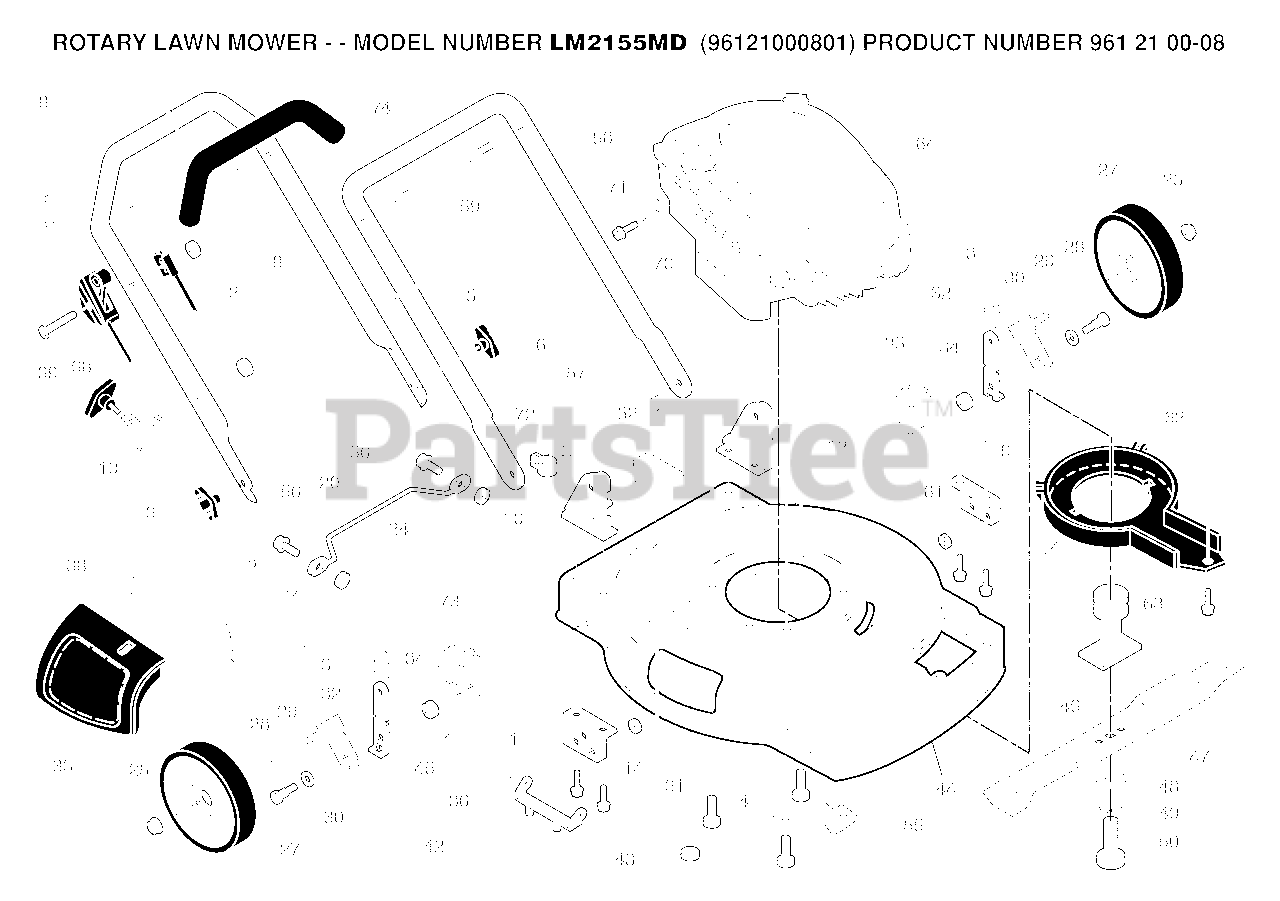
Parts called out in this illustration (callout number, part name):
2	ENGINE ZONE CONTROL CABLE
5	TIE GUIDE
6	KNOB, DEFLECTOR
10	HANDLE BRACKET ASM. RH
12	HANDLE BRACKET ASM. LH
14	SCREW 5/16-18
18	NUT
19	GUIDE.ROPE.STD.BLK.ZIN
25	HEX FLANGE LOCKNT
28	BOLT
29	BELLEVILLE WASHER
30	AXLE ARM
31	SELECTOR KNOB
34	RP SPACER HT ADJ
36	HINGE BRACKET
41	BOLT 3/8-16X1-1/8
42	TORSION SPRING
43	LOCKNUT
45	ROD.HINGE.COMBI-C
46	BLADE ADAPTOR / PULLEY
48	WASHER,HARDEN
49	LOCKWASHER
50	SCREW, HEX HD 3/8-24 X 1-3/8
52	DECAL.INTERNATIONL.CUTFINGER
55	BRACKET
57	HAIRPIN COTTER
59	BOLT, HANDLE 5/16-18X1.75
61	LOCKNUT PM
62	DEBRIS.SHIELD.21:.FGD
63	SCREW.HEX.WSH
68	THROTTLE CONTROL
70	CABLE CLAMP(ENGINE)
71	SCREW.HEX.HEAD.WASHER.10-16
72	CLIP.CABLE.BLK
74	GRIP.HANDLE.FOAM
